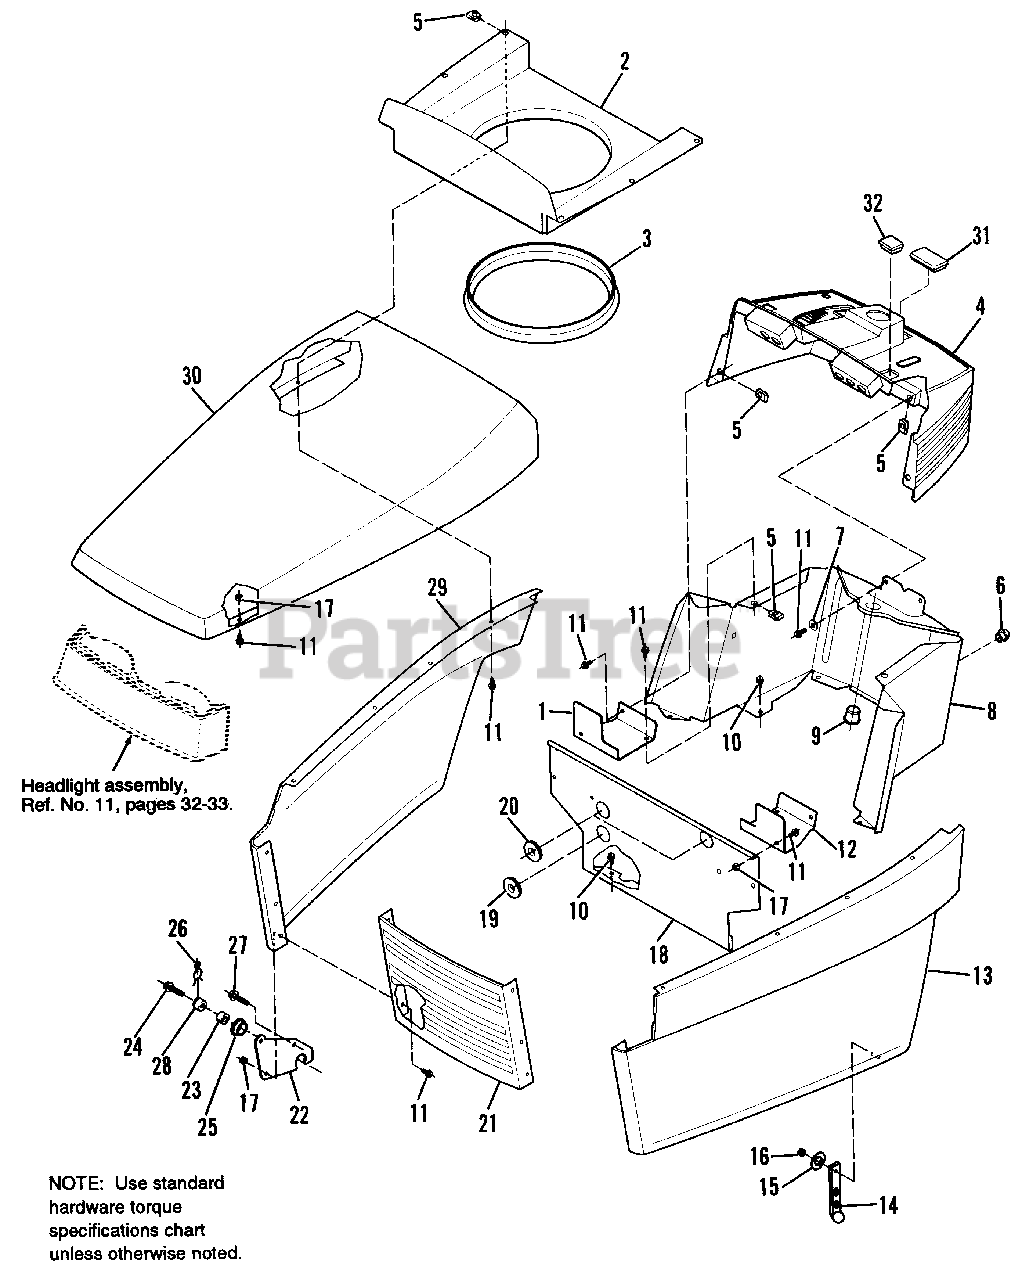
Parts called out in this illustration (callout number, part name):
1	SUPPORT, Bulkhead, R.H.
2	AIR DUCT (Hydro models only)
2	AIR DUCT (Gear models only)
3	MOLDING, Air Duct (Hydro models only)
3	MOLDING, Air Duct (Gear models only)
4	DASH ASSY. (Hydro models only)
4	DASH ASSY. (Gear models only)
5	PAL NUT, 1/4-20
6	PLUG, Bumper (Gear models only)
7	WASHER, Plain, 1/4
8	DASH, Lower
9	BUSHING, Nylon
10	SCREW, Tapttie, 1/4-20 x 1/2
11	CAPSCREW, Whizlock, 1/4-20 x 5/8
12	SUPPORT, Bulkhead, L.H.
13	SIDE PANEL ASSY., L.H.
14	STRAP, Hood
15	WASHER, Special
16	NUT, Hex, Nylon, Lock, #10-24
17	NUT, Hex, Nylon, Lock, 1/4-20
18	BULKHEAD
19	GROMMET, Wire Harness
20	GROMMET, Bulkhead
21	GRILLE
22	HINGE, Hood
24	SCREW, Taptite, 5/16-18 x 1
25	SPACER, Hood
26	CLIP, Hairpin
27	SCREW, Taptite, 5/16-18 x 5/8
28	PIVOT, Hood
29	SIDE PANEL ASSY., R.H.
30	HOOD
31	PLUG, Hole, Hourmeter (Hydro models only)
32	PLUG, Hole, Electric Lift (Hydro models only)
